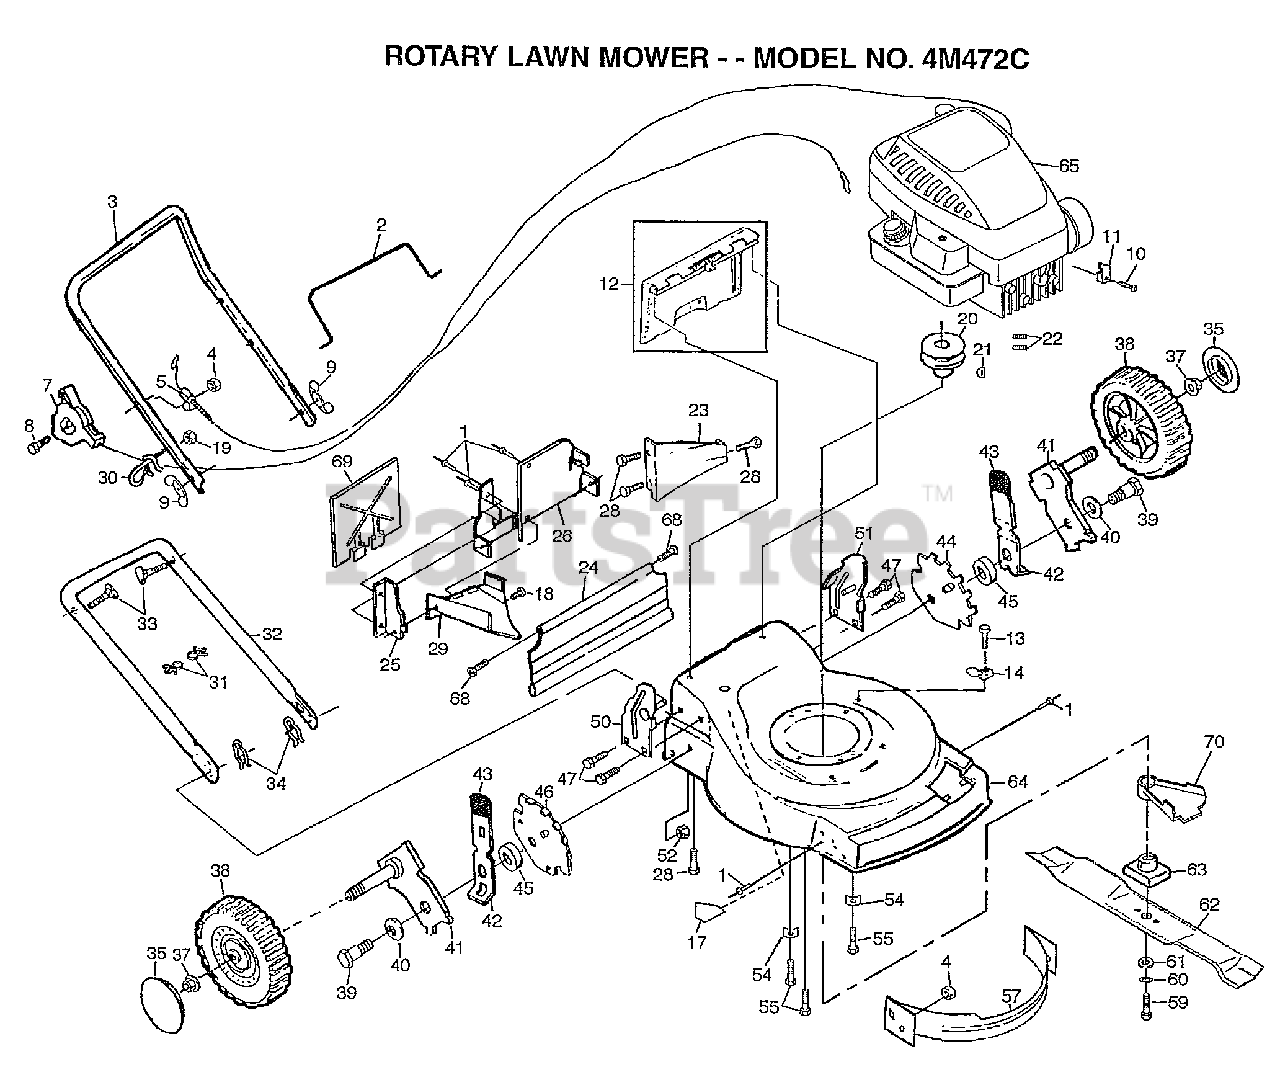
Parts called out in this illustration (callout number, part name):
1	BLIND RIVET
2	BAIL.CNTRL.DLX.ST
5	CABLE.ASM
7	CONTROL.THL.49.35
8	SCREW.HXHD.WASH.
9	"NUT,WING PM"
10	SCREW PM
11	CABLE CLAMP
12	KIT.DOOR.REAR
13	TAPPING SCREW
14	GUIDE CLIP PM
17	DECAL HYT
18	SCREW.HXTAP.10-24
19	NUT
20	ENGINE.PULLEY.FWG
21	HI PRO KEY PM
22	SCREW
23	REAR BAFFLE
24	SKIRT.REAR.FGD.22
26	PLATE.BACK
28	SCREW
29	DISCHARGE BAFFLE
30	ROPE GUIDE
32	LOWER HANDLE
33	BOLT.HANDLE.LM
34	HAIRPIN COTTER
35	HUB CAP
37	HEX FLANGE LOCKNT
38	WHEEL.8X2.PR.RAD.
39	BOLT SHLD 3/8-16
40	"WASHER, BELLEVIL."
41	ARM.AXLE.ASM.BZP.
42	SPRING SELECTOR
43	KNOB PM
44	BRACKET.ADJ.9.LH
46	BRACKET.ADJ.9.RH
47	SCREW.HXWS.5/16
50	BRACKET.HDL.RH.
51	BRACKET.HDL.LH.
52	LOCKNUT PM
55	BOLT.ENG.3/8-16
59	SCREW
60	LOCKWASHER
61	"WASHER,HARDEN"
62	"BLADE.MULCH.22"""
63	ADAPTOR.BLADE.LM
64	KIT.HSG.22RD.FWGD
68	HINGE SCREW
69	MULCHER PLATE
